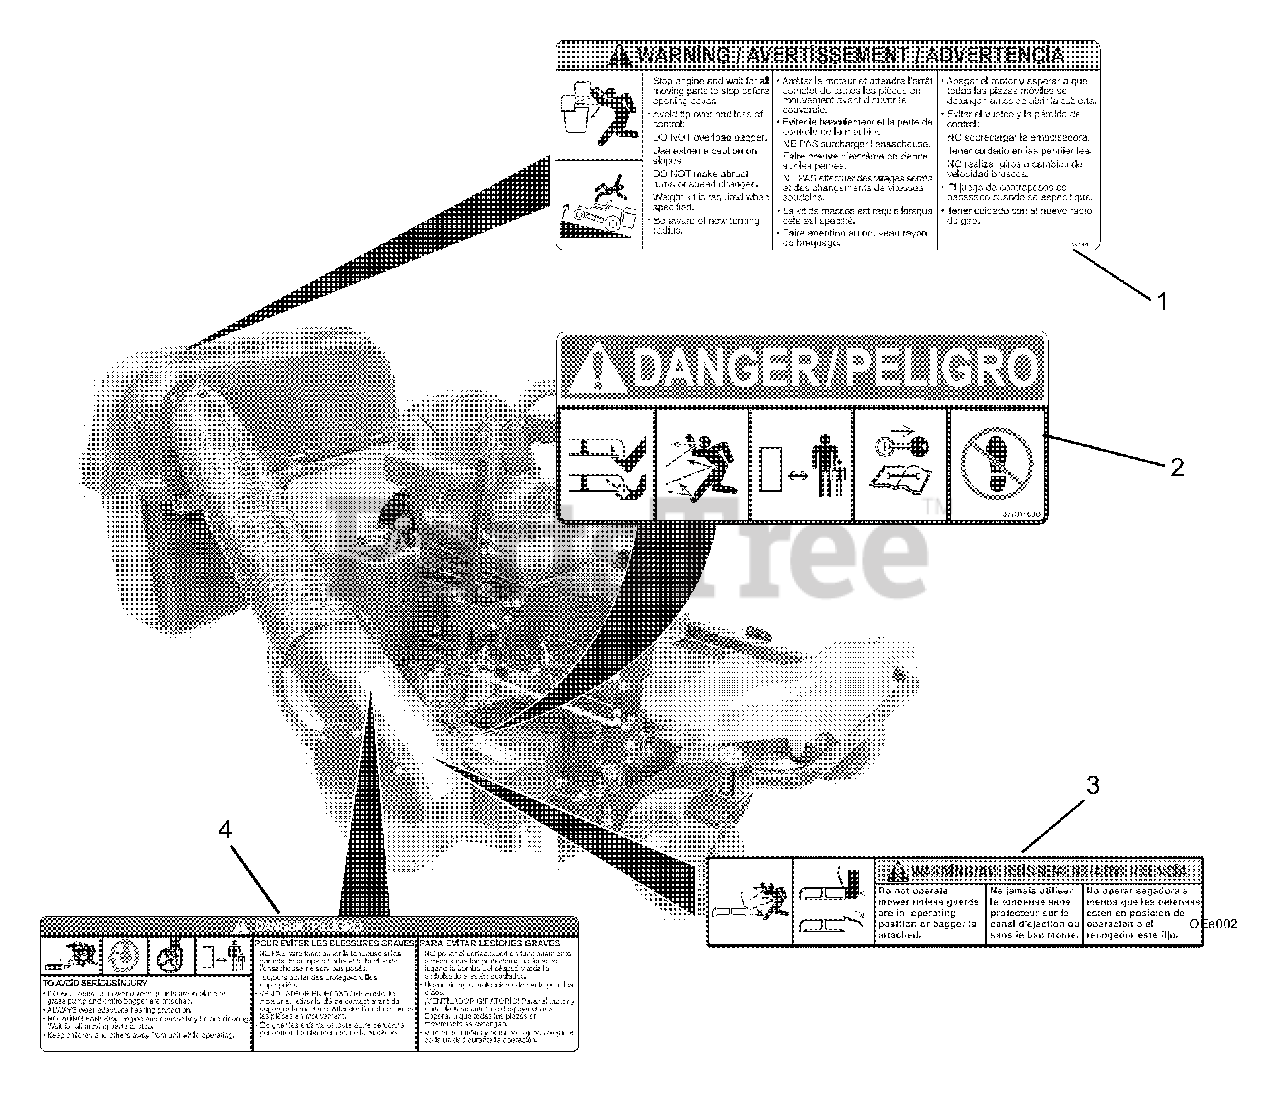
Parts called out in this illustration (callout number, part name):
1	Bagger Cover Decal
2	Mower Pan Danger Decal
3	Warning Decal
4	Grass Pump Caution Decal
